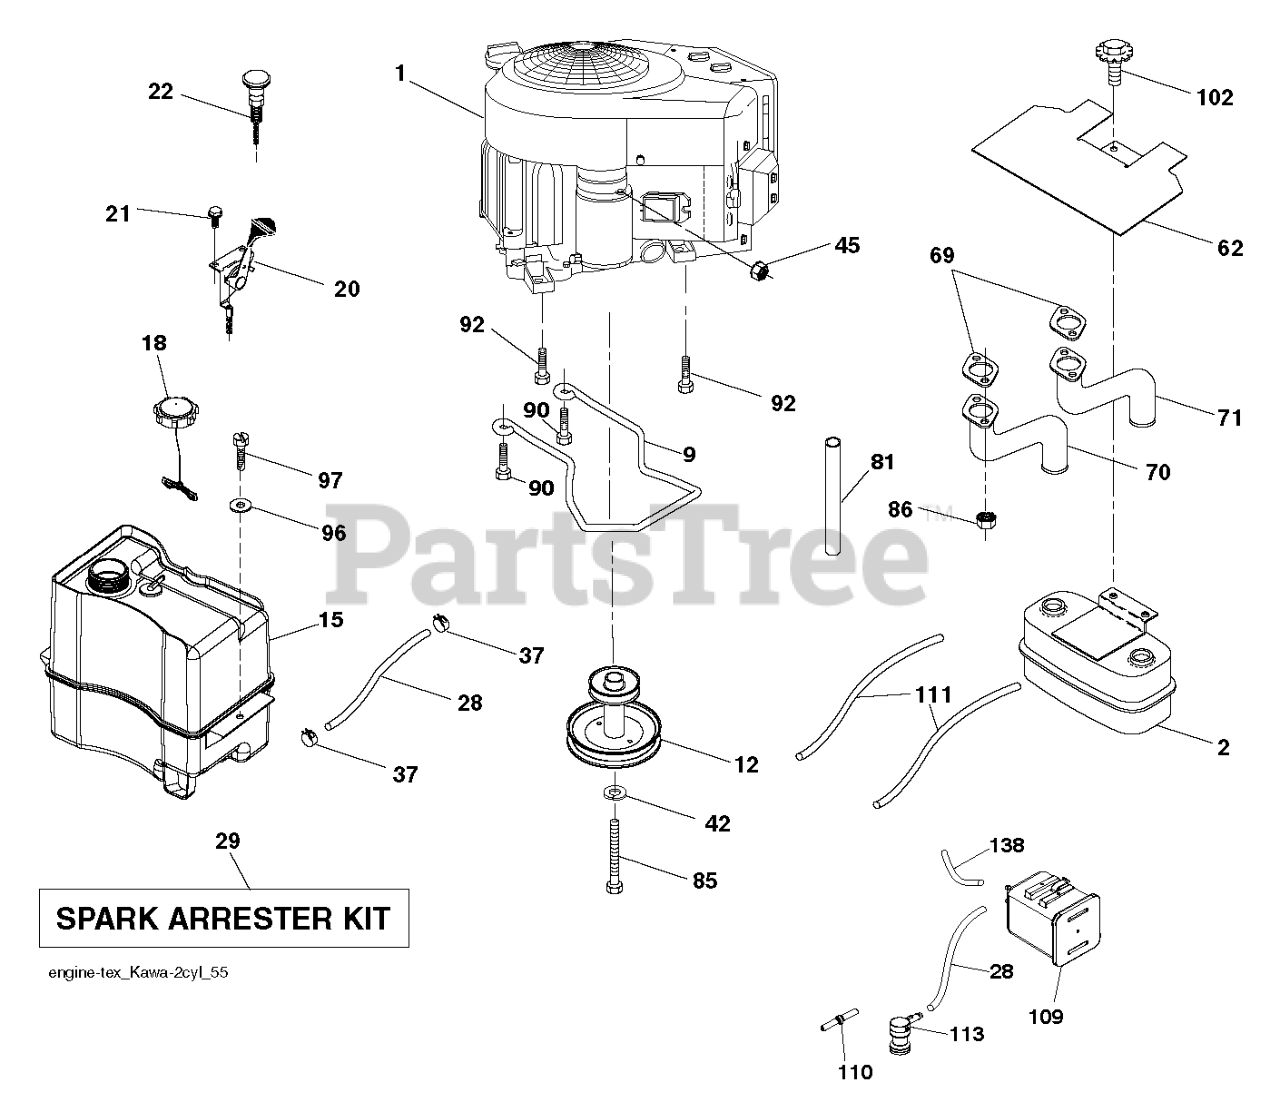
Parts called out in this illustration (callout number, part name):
2	MUFFLER.ASM.TWIN.MNTG.BRACKET
9	KEEPER.BELT.ENG.4.25"2.BLT.431
12	PULLEY.ENGINE
15	TANK.ASM.FUEL.3GA.CARB.17
18	FUEL CAP
18	CAP ASSY FUEL 3" GRAY
20	CONTROL.THROTTLE.COBRA.BLACK
21	SCREW.#10 X 0.750.BOS
22	CONTROL, CHOKE
28	LINE.FUEL.64"REAR.EMIS
29	KIT.SPARK ARRESTOR 794945 B&S
37	HOSE CLAMP
42	LOCKWASHER
45	NUT
62	SHIELD.HEAT.MUFFLER
70	TUBE.EXHAUST.RH.FR961/FR730
71	TUBE.EXHAUST.LH.FR961/FR730
81	TUBE, DRAIN OIL ASM.
85	BOLT.HEX.7/16-20X4.GR5.1.5BLUE
86	BLADE ADAPTER
90	SCREW 3/8-16X1
92	SCREW 3/8-16X1
97	SCREW HEXWSHR 1/4-20X3/4
102	SCREW
109	CANNISTER, CARBON
110	VALVE.ASM.ANTI-SLOSH
111	RP PURGE LINE
113	VALVE.SLANT.CARTRDG.90 DEG.TEX
138	PURGE.LINE.36"REAR.CALIFORNIA
